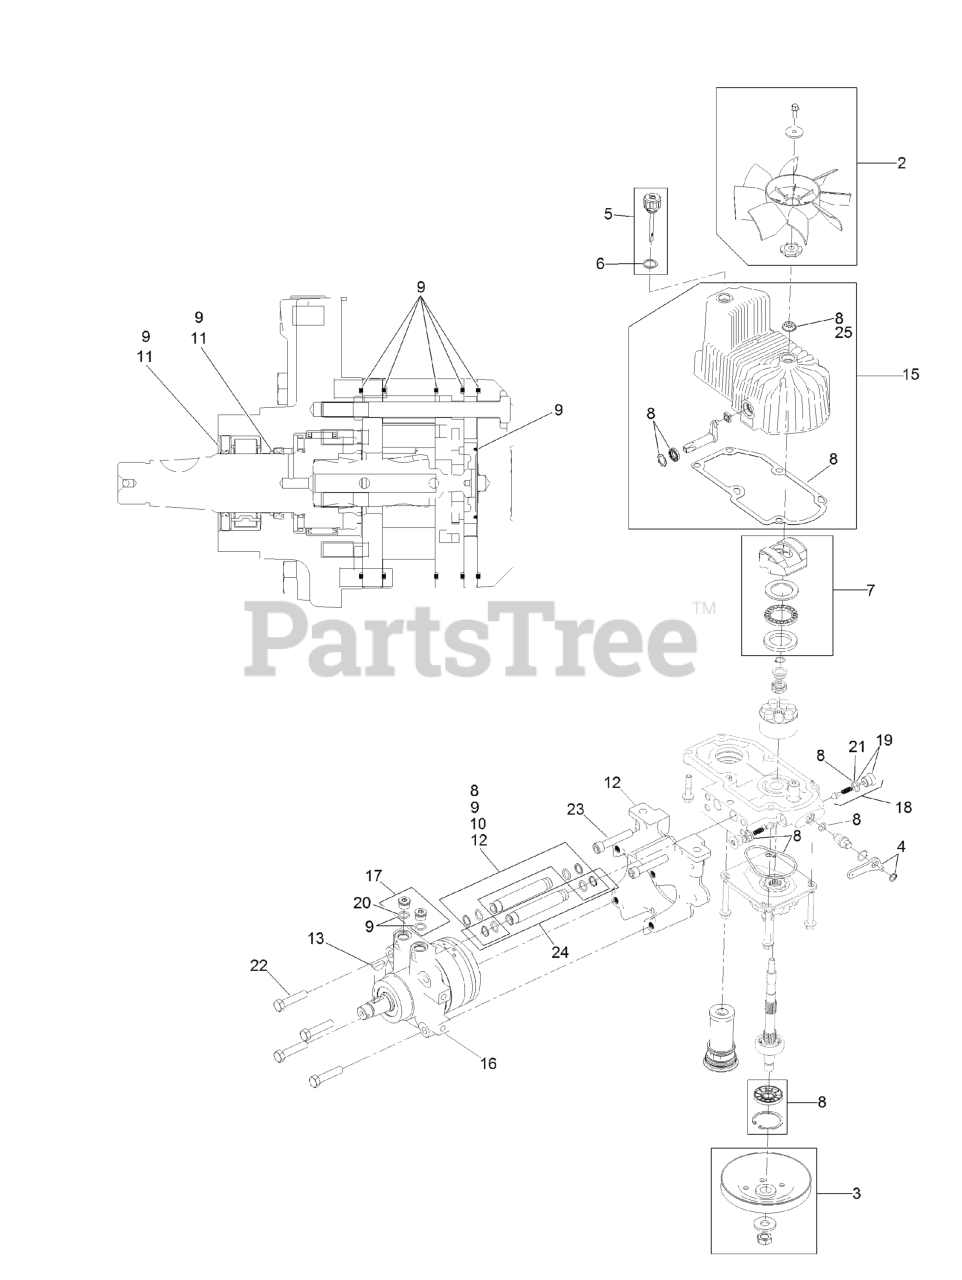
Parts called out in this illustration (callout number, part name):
2	FAN KIT
3	PULLEY KIT
4	HANDLE-BYPASS VALVE, HYDRO
5	DIPSTICK-HYDRO W/GASKET
6	GASKET-DIPSTICK, HYDRO
7	SWASH BLOCK KIT
8	PUMP SEAL KIT
9	MOTOR SEAL KIT
10	TUBE SEAL KIT
11	OUTPUT SHAFT SEAL KIT
12	NOSE CUP-UHT
13	KEY-WOODRUFF
15	HOUSING-HYDRO, LH
16	MOTOR-HYDRAULIC LH 240CC
17	MAGNETIC PLUGS SERVICE KIT
18	CHECK VALVE ASM
19	PLUG-CHECK (W/O-RING)
21	O-RING-CHECK VALVE
22	SCREW HH
23	SCREW-HSH
24	HYDRAULIC TUBE KIT
25	SEAL-FAN DRIVE
26	PULLER-PULLEY
27	ROTATING KIT
